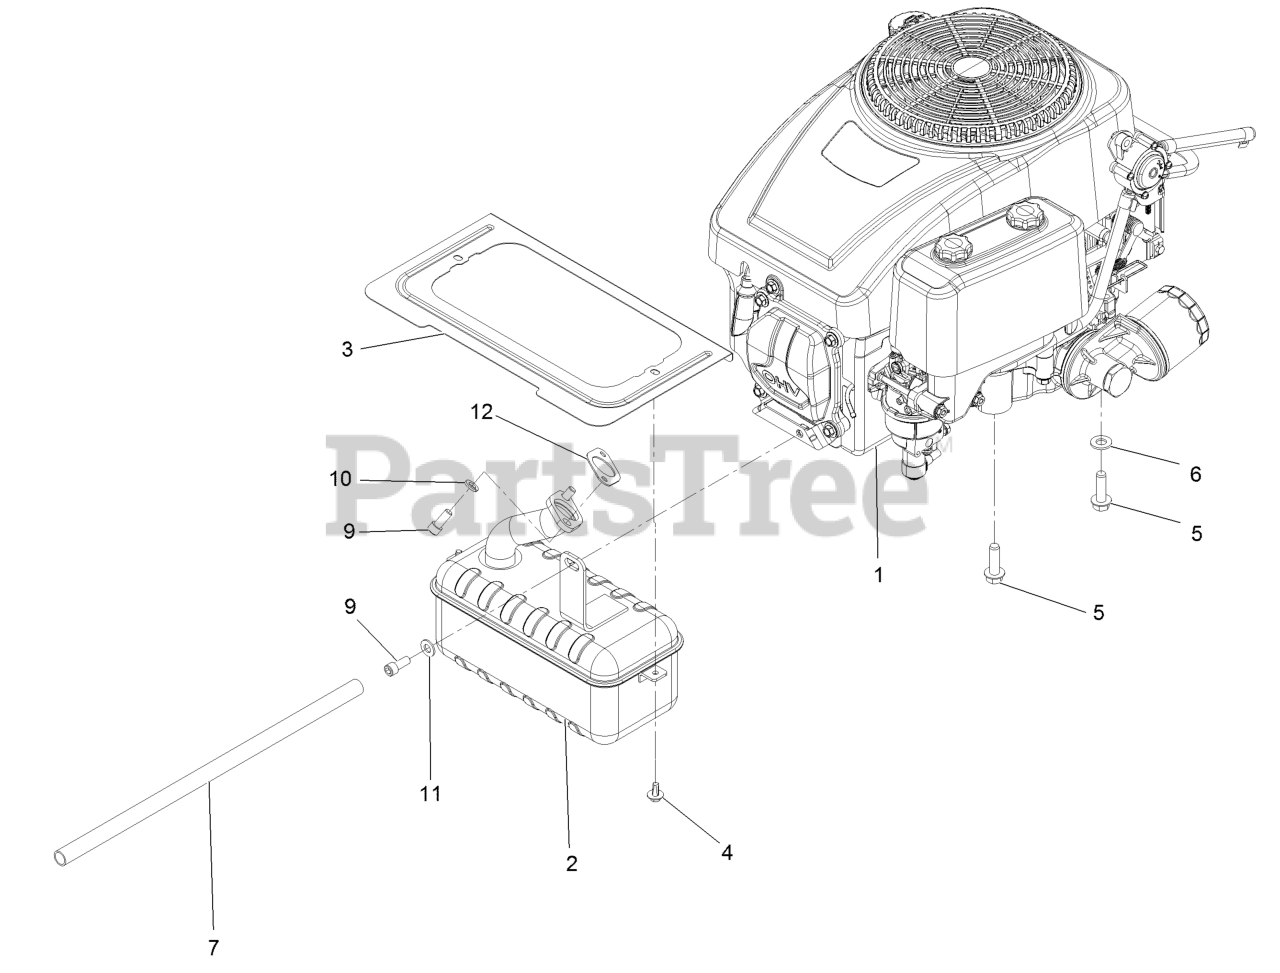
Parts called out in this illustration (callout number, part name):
1	Engine-Lc1P92F-1
2	Muffler
3	Shield-Heat
4	Screw-HHF 1/4-20 X 1/2
5	Screw-HWH 3/8-16 X 1 1/4 Taptite
6	Washer-3/8 SAE
7	Hose-Oil Drain
9	Screw-HSH 5/16-18 X 3/4
10	Washer-Lock 5/16
11	Washer-5/16 SAE
12	Gasket-Exhaust
